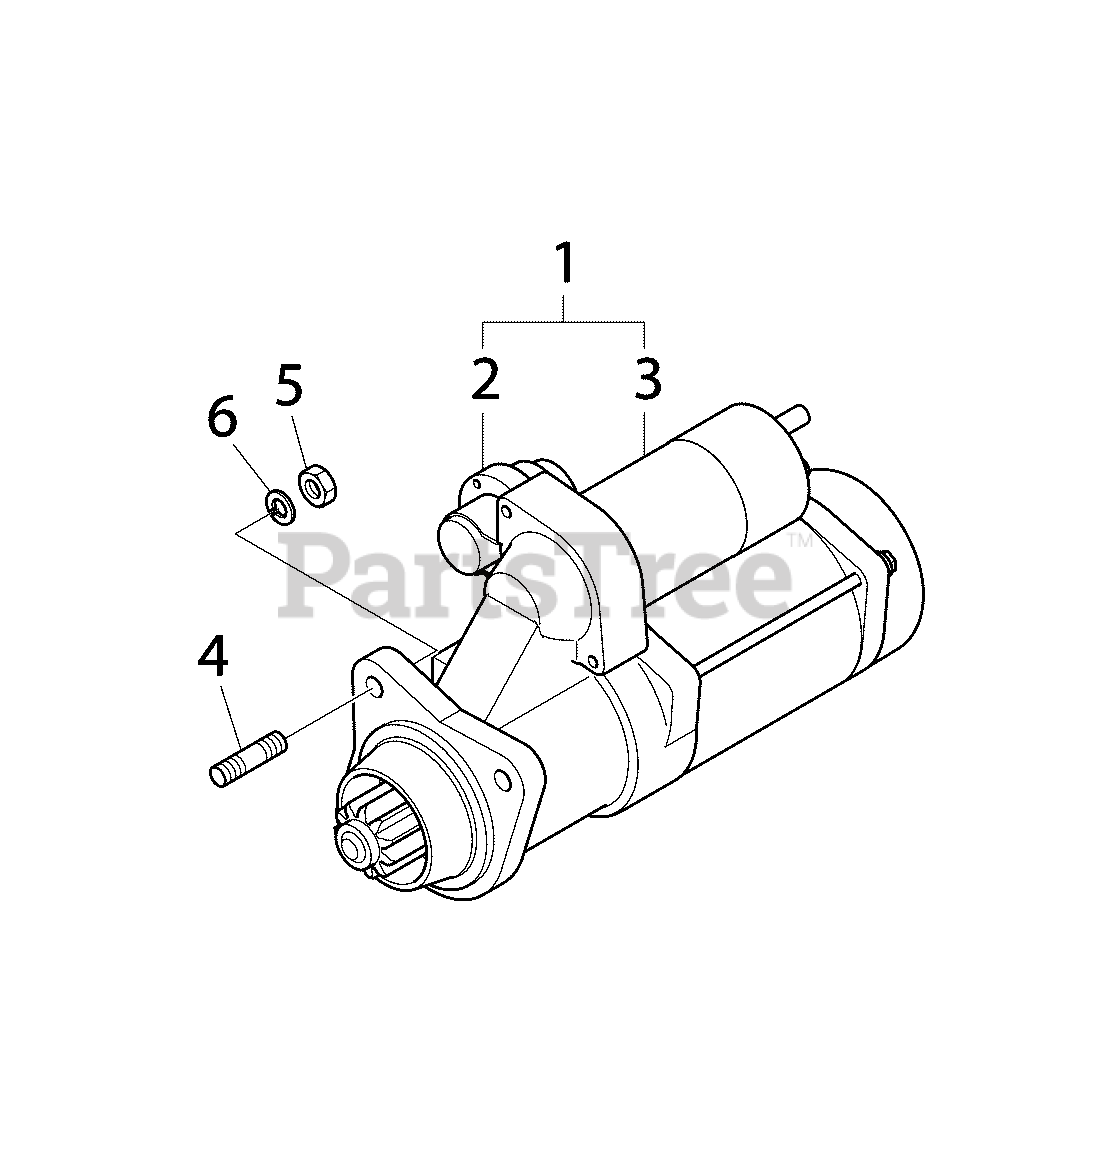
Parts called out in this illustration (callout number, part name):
1	STARTER
2	* RELAY
3	* MAGNETIC SWITCH
4	* STUD BOLT
5	* NUT, HEX
6	* WASHER, SPRING
